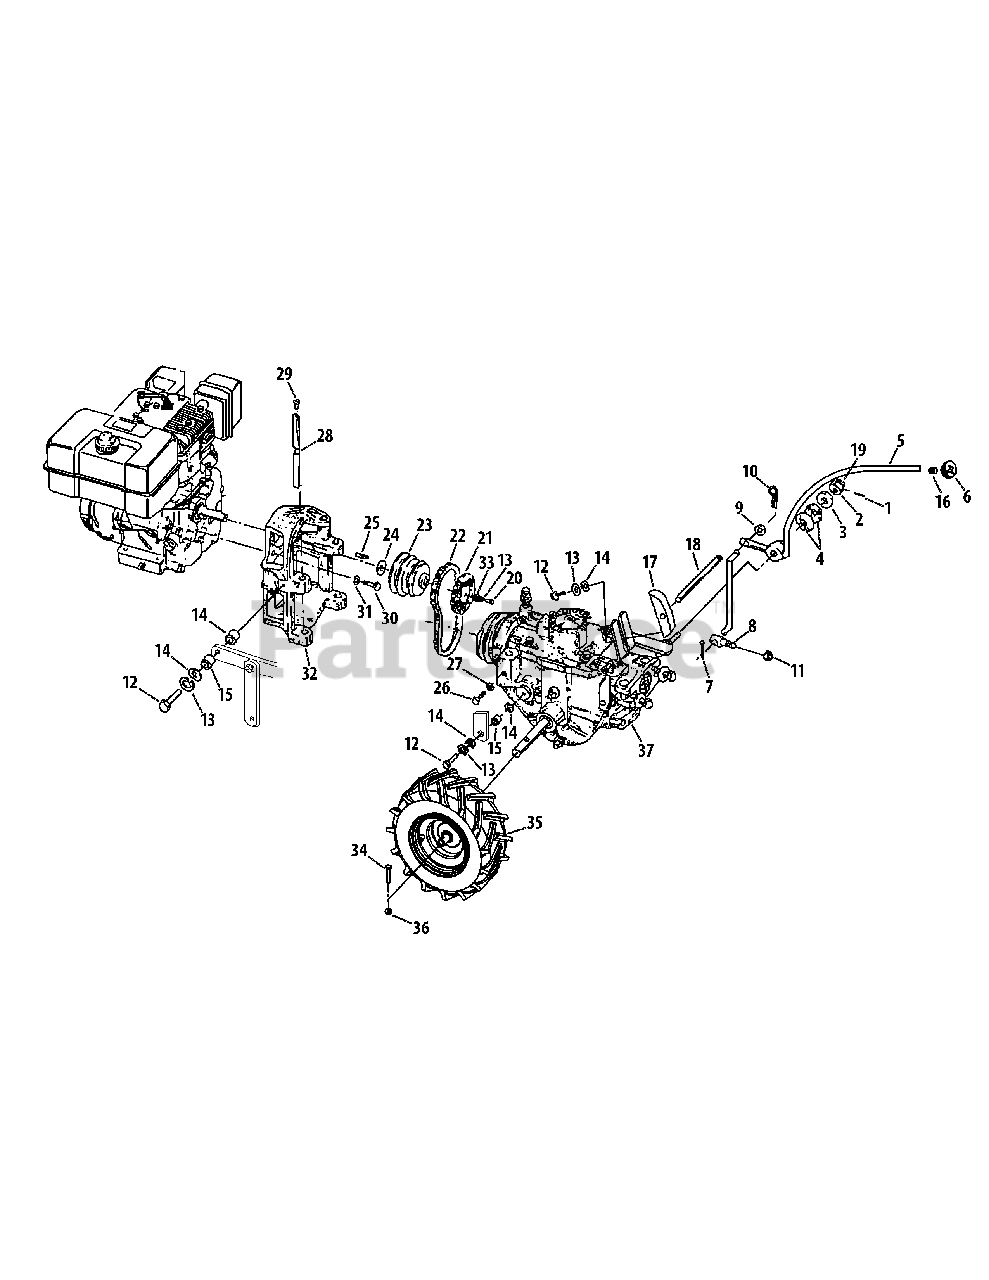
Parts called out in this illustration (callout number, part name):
1	Spring Pin, 1/8"
2	Flat Washer, .510 x 1.0 x .125
3	Shoulder Washer, 1.25 x .50 x .25
4	Disc Spring Washer
5	Wheel Speed Shift Lever
7	Cotter Pin, 3/32" x 1"
9	Flat Washer, .344 x .688 x .065
10	Hair Pin Cotter
11	Hex Locknut, 5/16"-18
12	Hex Head Screw, 3/8"-16 x 1"
13	Lockwasher, 3/8"
14	Flat Washer, .406 x .810 x .051
15	Bushing Spacer, .5 x .375 x .3
16	Retaining Ring
17	Belt Adjustment, 3-7/8"
18	Belt Adjustment Rod
19	Hex Nut, 1/2"-20
20	Hex Head Screw, 3/8"-24 x 1.75
21	Reverse Disc
22	Forward Drive Belt
23	Engine Power Take-off Pulley
24	Flat Washer, .766 x 1.0 x .031
24	Flat Washer, .766 x 1.0 x .062
25	Engine Pulley Key, 3/16"x 2-1/2"
26	Hex Head Screw, 5/16"-18 x 1"
27	Hex Nut, 5/16"-18
28	Engine Mounting Bar
29	Thread Protector Plug
30	Hex Head Screw, 5/16"-24 x 1.125
31	Lockwasher, 5/16"
33	Flat Washer, .406 x 1.0 x .105
34	Hex Screw, 1/4"-20 x 1-1/2"
35	Wheel Assembly, 16 x 4.6 x 8"
35	Tire, 16.2 x 4.6
36	Hex Flange Nut, 1/4"-20
37	Clutch Bracket
